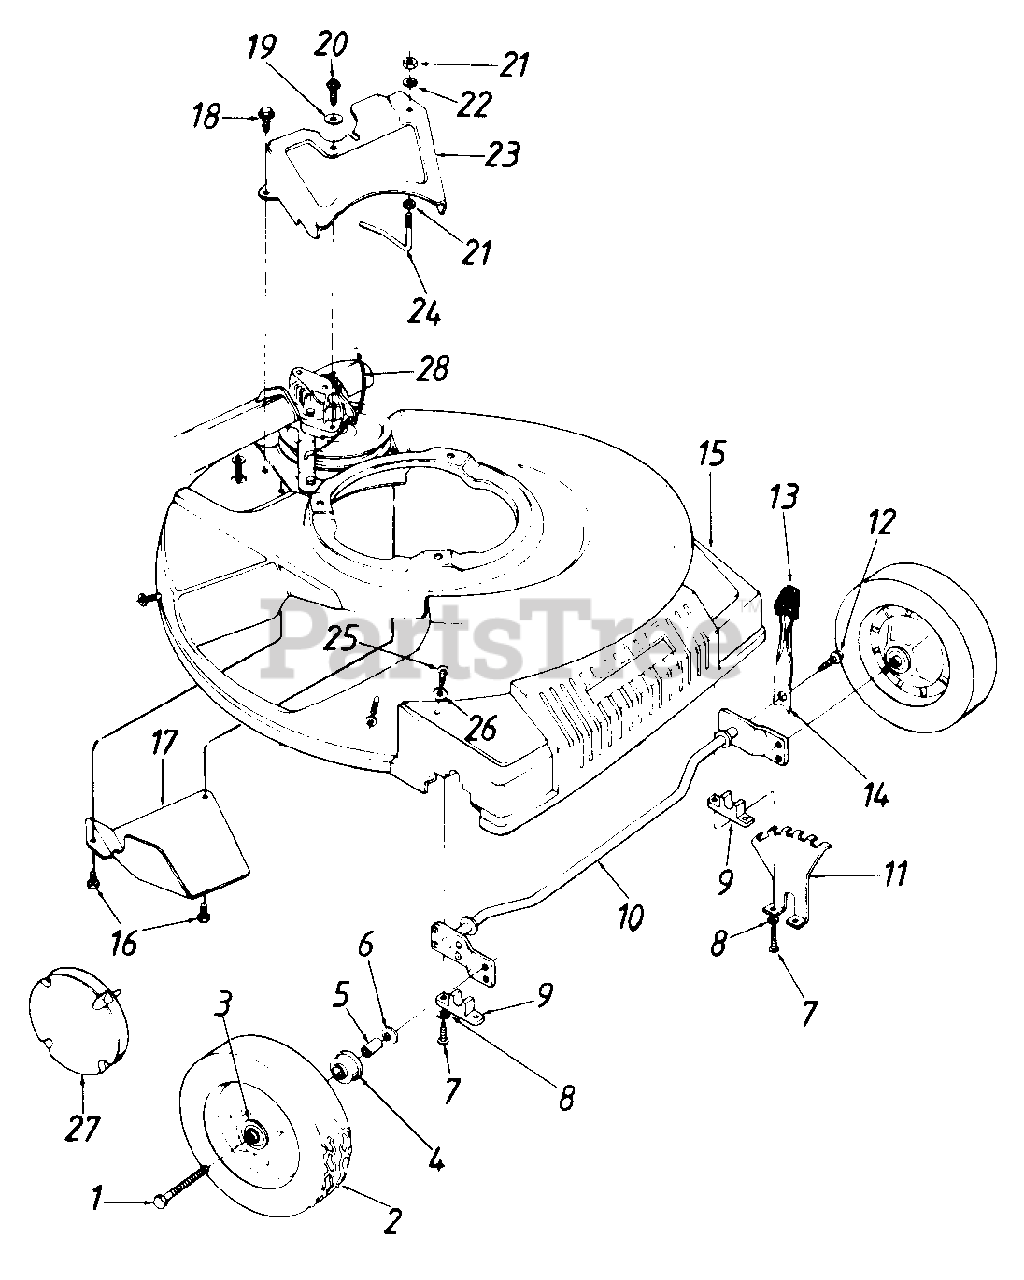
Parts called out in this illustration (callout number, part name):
1	Hex Bolt 3/8-16 x 1.75" Lg.
2	Wheel Ass'y. Comp. 8 x 1.75
3	Flange Ball Brg. 3/8" I.D.
4	Flange Ball Brg. .501" I.D.
5	Spacer
6	Bell-Wash. .400" I.D. x .88
7	Hex Wash. Hd. B-Tap Scr. 1/4-20
8	L-Wash. 1/4" I.D.
9	Block Bushing
10	Axle Ass'y.
11	Height Adj. Bracket
12	Hex Wash. Hd. B-Tap Scr. 1/4-20 x .75" Lg.
13	Knob
14	Spring Lever
15	Plastic Front End
16	Hex B-Tap Scr. 1/4-.38"
19	Bell-Wash. .265" I.D. x .75"
20	Hex Wash. Hd. B-Tap Scr. 1/4 x .62"
21	Hex Nut 1/4-20 Thd.
22	L-Wash. 1/4 I.D.
23	Transmission Belt Guard
24	S.P. Belt Guard
25	Truss B-Tap Scr. 5/16 x .75" Lg.
26	Bell-Wash. 5/16" I.D. x 5/8
27	Hub Cap
28	S.P. Cable 50" Lg.
